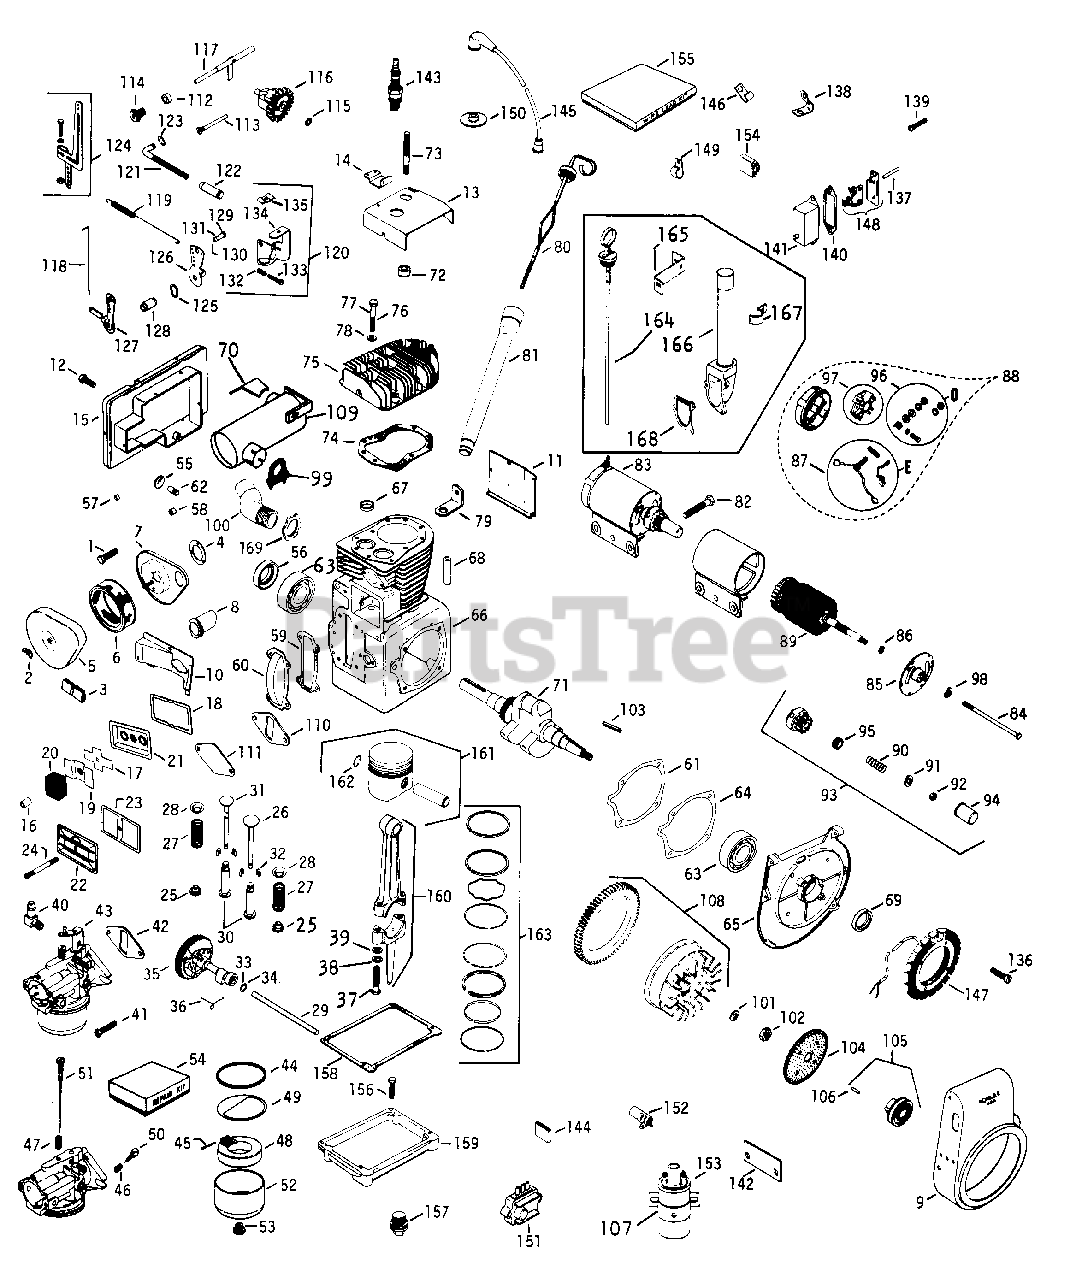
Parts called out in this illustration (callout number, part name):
1	Screw, 10-32 X 1/2 Znd Hex Hd Self Tap
2	Nut, Wing
4	Gasket, Air Cleaner
5	Cover, Air Cleaner
6	Element, Air Cleaner
7	Base, Air Cleaner
8	Tube, Air Cleaner
9	Housing, Blower
10	Baffle, Side
11	Baffle, Cylinder
12	Screw, 1/4-20 X 3/4 Hex Hd
13	Baffle, Head
14	Bracket, Lifting
16	Seal, Breather
17	Reed, Breather
18	Gasket, Cover
19	Baffle, Breather
20	Filter, Breather
21	Plate, Breather
22	Cover, Breather
23	Gasket, Valve Cover
24	Stud, Valve Cover
25	Retainer, Valve Spring
26	Valve, Intake
27	Spring, Valve
28	Retainer, Valve Spring
29	Pin, Camshaft
30	Tappet Assy
31	Valve, Exhaust
32	Keeper, Valve Spring
33	Shim, Camshaft, .005
34	Shim, Camshaft, .010
35	Camshaft Assy
36	Spring, Camshaft Actuating
37	Screw, Connecting Rod
38	Washer, 3/8 Heavy Lock
39	Washer, Connecting Rod
40	Elbow, Hose Connector
41	Screw, 5/16-18 X 1 Hex Hd Sems
42	Gasket, Carburetor
43	Carburetor Assy
44	Gasket, Fuel Bowl
45	Pin, Hinge
46	Spring, Idle Adjusting Screw
47	Spring, High Speed Needle
48	Float & Lever Assy
49	Gasket, Bowl Baffle
50	Screw, Idle Adjusting
51	Needle, High Speed
52	Bowl, Fuel
53	Screw w/Gasket, Fuel Bowl
54	Kit, Carburetor Repair
55	Plug, 1-1/8 Expansion
56	Seal, Rear Oil
57	Plug, 1/2 Cup
58	Bearing, Crankcase Needle
59	Gasket, Cam Cover
60	Cover, Cam
61	Gasket, Bearing Plate, .010
62	Shaft, Governor
63	Bearing, Crankcase Ball
64	Gasket, Bearing Plate
65	Plate, Bearing
66	Block, Cylinder
67	Insert, Exhaust Valve
68	Guide, Valve
69	Seal, Front Oil
70	Deflector, Exhaust
72	Spacer
73	Stud, Cylinder Head
74	Gasket, Cylinder Head
75	Head, Cylinder
76	Screw, 3/8-16 X 1-1/2 Znd Hex Hd Cap Type 8
77	Screw, 3/8-16 X 1-3/4 Znd Hex Hd Cap Type 8
78	Washer, Head
79	Bracket, Baffle Mounting
80	Dipstick w/Shoulder Mount
81	Tube, Oil Fill w/Shoulder Mount
82	Bolt, Shoulder
83	Starter Assy
85	Cap Assy, Drive End
86	Washer, Armature Thrust
87	Kit, Starter Brush
88	Cap Assy, Commutator End
90	Spring, Anti-Drift
91	Spacer, Stop Gear
92	Nut, 5/16-24 Hex Lock
93	Kit, Starter Drive w/Shim
94	Cover, Dust
95	Spacer
96	Kit, Hardware
97	Kit, Brush Holder
98	Washer, 1/4 Znd Reg Lock
99	Clamp Assy, Muffler
100	Elbow, Exhaust
102	Nut, 5/8-18 Znd Hex Lock
103	Key, 3/16 X 1-3/8 Sq Parallel
104	Screen, Grass
105	Cup Assy, Flywheel Drive
106	Pin, Flywheel Drive Cup
107	Clamp, Ignition Coil
108	Flywheel Assy
109	Muffler Assy
110	Gasket, Pump Cover
111	Cover, Pad
112	Spacer
113	Pin, Governor Stop
114	Bushing, Governor
115	Washer, Thrust
116	Gear, Governor
117	Shaft, Governor
118	Linkage, Choke
119	Spring, Governor
120	Bracket Assy, Control
121	Rod, Ball Joint
122	Body, Ball Joint
123	Retainer, Throttle Rod
124	Lever, Governor
125	Washer, Tension
126	Lever, Throttle Control
127	Lever, Choke Control
129	Clamp, Swivel Wire
130	Washer, 9/32 X 5/8 X .062 Znd
131	Screw, 1/4-20 X 1-1/4 Hex Hd Sems
132	Spring, Adjusting
133	Screw, Throttle
134	Bracket, Control
135	Clamp, Wire
136	Screw, 10-24 X 3/8 Fil Hd Mach
137	Rod, Breaker
138	Clip, High Tension
139	Screw, 10-24 X 1 Znd Pan Hd Mach
140	Gasket, Breaker Cover
141	Cover, Breaker
142	Bar, Coil Bracket Back Plate
143	Plug, Spark (Champion)
144	Connector
145	Kit, Hi-Tension Lead
146	Clip, Terminal
147	Kit, Stator
148	Breaker & Bracket Assy
149	Clip, Cable
150	Grommet, Spark Plug
151	Regulator Assy
152	Condenser, Ignition Coil
153	Coil, Ignition
155	Kit, Wire Lead Cable
156	Screw w/Lock Washer, 3/8-16 X 1-1/2 Znd Hex Hd
157	Plug, Drain
158	Gasket, Oil Pan Base
159	Base, Oil Pan
160	Rod Assy, Connecting, Std
161	Piston Assy, Std
162	Retainer, Piston Pin
163	Ring Set, Piston, Std
164	Dipstick w/o Shoulder Mount
165	Bracket, Dipstick Tube
166	Tube Assy, Oil Fill w/o Shoulder Mount
167	Clamp, Conduit
168	Gasket, Oil Fill Tube
169	Nut, Lock
